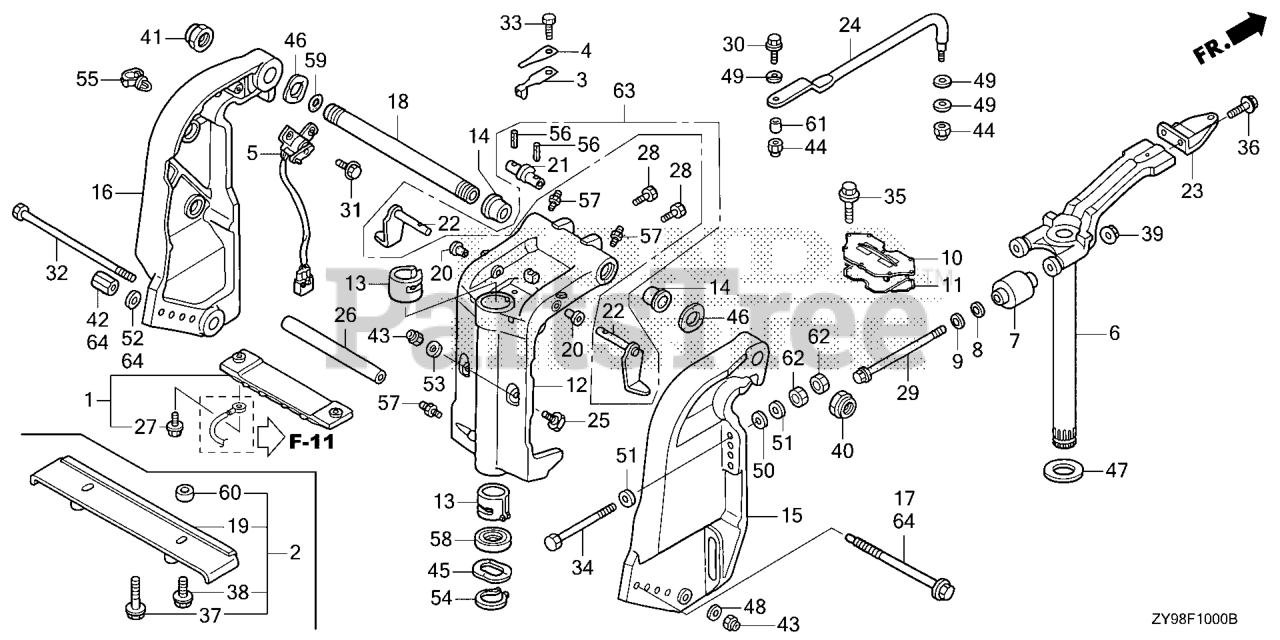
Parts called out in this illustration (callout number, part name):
1	METAL KIT, ANODE Use from Frame SN 4800343.
2	PLATE KIT, SPLASH
3	SPRING, CLICK
4	SPRING, CLICK ASSIST
5	SENSOR ASSY., TRIM ANGLE
6	FRAME, MOUNTING
7	MOUNT, RUBBER (UPPER)
8	RUBBER, MOUNT STOPPER (UPPER)
9	STOPPER, MOUNT (UPPER)
10	COVER, MOUNT (UPPER)
11	SEAL, MOUNT COVER (UPPER)
12	CASE, SWIVEL *NHB14M* (AQUA MARINE SILVER METALLIC)
13	LINER, SWIVEL CASE
14	BUSH, SWIVEL CASE
15	BRACKET, R. STERN *NHB14M* (AQUA MARINE SILVER METALLIC)
16	BRACKET, L. STERN *NHB14M* (AQUA MARINE SILVER METALLIC)
17	ROD, ADJUSTING
18	SHAFT, TILTING
19	PLATE, SPLASH
20	BUSH, TILT ARM
21	BRACKET, TILTING
22	STOPPER, TILT
23	PLATE, STEERING
24	ROD, STEERING
25	RECEIVER, THRUST
26	COLLAR, CYLINDER (LOWER)
27	BOLT, FLANGE (6X23) Use from Frame SN 4800343.
28	BOLT (1/4-28UNF)
29	BOLT, HEX. (12X186)
30	BOLT (3/8-24UNF)
31	BOLT, FLANGE (6X20) (ENGINE NO.)
32	BOLT, HEX. (10X235)
33	BOLT, HEX. (6X14)
34	BOLT, HEX. (12X119)
35	BOLT, FLANGE (8X25)
36	BOLT, FLANGE (10X25)
37	BOLT, FLANGE (6X25) (SUS-D)
38	BOLT, FLANGE (6X16) (SUS)
39	NUT, FLANGE (12MM)
40	NUT, SELF-LOCK (7/8-14UNF)
41	NUT, SELF-LOCK (M25X2.0)
42	NUT, ADJUSTER ROD
43	NUT, FLANGE (10MM)
44	NUT, SELF-LOCK (3/8-24UNF)
45	WASHER, WAVE (40MM)
46	WASHER, WAVE (26MM)
47	WASHER, THRUST (34MM)
48	WASHER, PLAIN (10MM)
49	WASHER (10MM)
50	WASHER, PLAIN (12MM)
51	WASHER, PLAIN (12MM)
52	WASHER, PLAIN (12MM)
53	WASHER, PLAIN (10MM)
54	CIRCLIP (OUTER) (39MM)
55	CLIP, WIRE HARNESS
56	PIN, SPRING (2.5X20)
57	NIPPLE, GREASE
58	OIL SEAL (39.5X52X6) (ARAI)
59	O-RING (15.54X2.26)
60	COLLAR, SPLASH PLATE
61	COLLAR, STEERING ROD
62	NUT, HEX. (12MM)
63	STOPPER KIT, TILT
64	ROD, ADJUSTING
